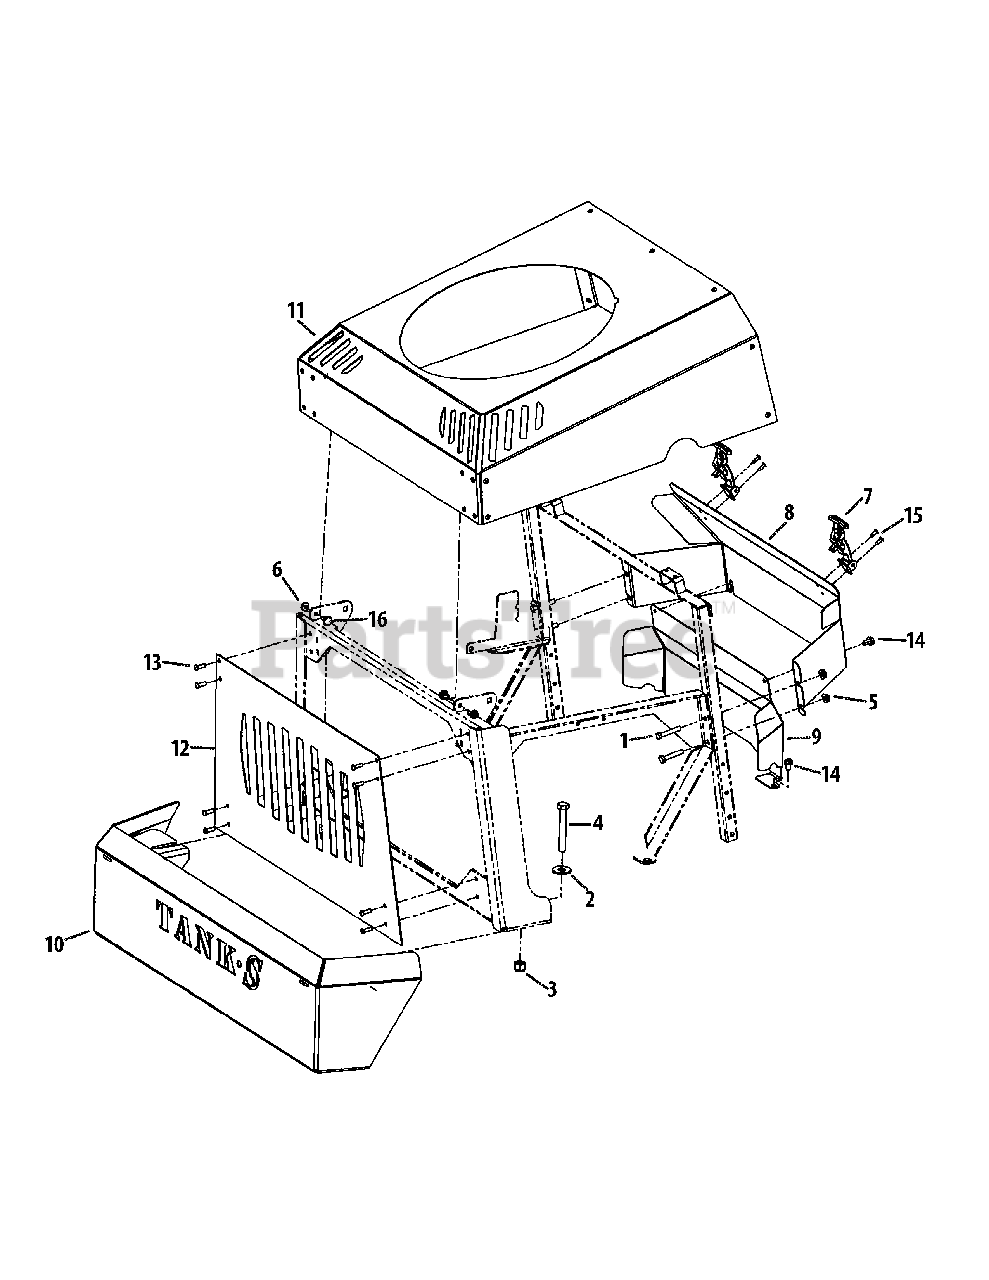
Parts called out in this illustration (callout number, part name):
1	Hex Screw, 5/16-18 x 1.75
2	Washer, .563 x 1.38 x .109
3	Nut, 1/2-13
4	Hex Screw, 1/2-13 x 3.50
5	Flange Counter Lock Nut, 5/16-18
6	Flange Top Luck Nut, 1/4-20
7	T-Handle Draw Latch
8	Top Guard Plate
9	Front Bottom Guard Plate
10	Bumper Assembly
11	Hood Assembly
13	Machine Screw, 1/4-20 x 0.750
14	Hex Washer Screw, 5/16-18 x 0.625
15	Rivet, 3/16
16	Shoulder Screw, .375 x .181
